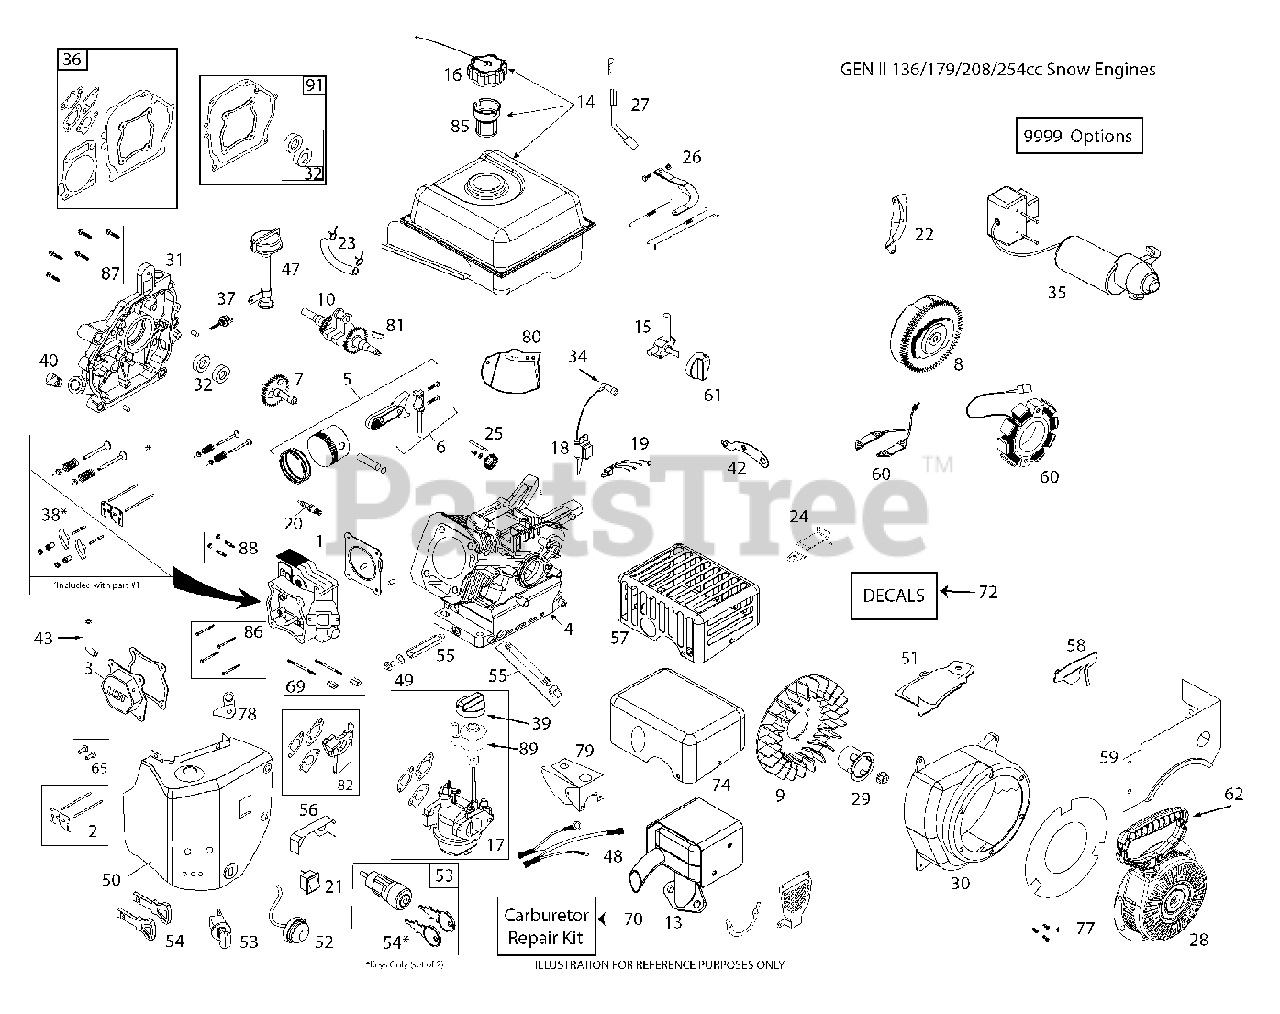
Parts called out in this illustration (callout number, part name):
1	Cylinder Head Assembly with Gasket, 254
2	KIT.PUSH.ROD.&.PLATE.W/VC.GASK
3	COVER.VALVE.W/GASKET.254CC
5	PISTON.&.ROD ASSEM.254CC
7	CAMSHAFT.MCR.W/GASKET.254CC
8	FLYWHEEL.ELEC.STRT.(8.MAGNETS)
9	KIT.COOLNG.FAN.SERV(SK208-4000
10	CRANKSHAFT.KEYED(#18).SNOW.254
13	MUFFLER.ASSEM.GEN2.SNOW.254CC
14	FUEL.TANK.SNOW.2.7L.BLACK.254C
15	FUEL.PETCOCK.SNOW(SKSN4900)
16	FUEL CAP OVERSIZED CLICK STYLE
17	Carburetor, LCT 254 with Idle-Down
18	COIL.ING.CDI.HI TEMP.SKSNO416.
20	PLUG.SPARK.PLAT.SKSN2404.1
21	SWITCH.ON/OFF(SKSN-0403)
22	SHIELD.FLYWHEEL.ELEC.STRT.208C
23	FUEL HOSE KIT
24	BRACKET.SPEED.CNTRL.FIXED.254C
25	GOVENOR.GEARS ASM(SK2082900)
26	KIT.GOVERNOR.ARM.&.LINK.254CC
27	KIT.GOVERNOR.CRANK(SK208-3100)
28	RECOIL.STRT.ROUND(BLK) SNOW
29	STRTER.CUP(NON-SLOT)SKSN0601.2
30	BLOWER HOUSING.LCT.208.ES W/OIL
31	CRANKCASE.CVR.PRESS.IN.HI-OIL.
32	Oil Seal Kit, 2 Pieces 254CC
34	SPARK.PLUG.BOOT.SNW,SKSN4691.1
35	ELEC.START.GEN2.SKSN0400.2
36	KIT.ENGINE.GASKET.254CC
38	KIT.ROCKER.ARM.W/GASKET.254CC
39	CHOKE.KNOW.SNOW(SKSN4500)
40	NON REMOVABLE PLUG
43	TUBE.BREATHER.LCT.208
47	High Oil Fill Tube Assembly
48	WIRE.HARNESS.SNOW
49	KIT.OIL.DRAIN.PLUG(SK2089911
50	KIT.HEATER.BOX.SNOW.254CC
52	PRIMER.BULB.WITH HOSE (SNOW)
53	SWITH.KEY.ASSEM.SNOW.SINGLE.ST
54	KEY SET(2 KEYS) SKSN0407.1
55	OIL PIPE DRAIN LCT 254
56	SHIELD.CARBURETOR.VAPOR
58	SHIELD.GOVERNOR.LINKAGE.254CC
59	FUEL TANK SKIRT SHIELD LCT 254
60	208CC 60W ALTERNATOR
61	FUEL KNOB-SNOW
62	HANDLE.RECOIL.DEL.SKSN0613.1
65	TAPPET.KIT.LCT.208CC
69	CARB.STUDS & COUPLING KIT.SNOW
70	Carburetor Repair Kit, LCT SK9900
74	Muffler Heat Shield Cover
77	Recoil Bolt Kit, LCT
79	COVER.CARBURETOR.SNOW
80	SHIELD.GOVERNOR.LINK.SNOW.254C
81	Flywheel Keys, 136/291cc 5-Pack
82	Carburetor Spacer, 208cc Lct
85	Fuel Tank Strainer, LCT 208cc
86	KIT.BOLT.CYLINDER.HEAD.(4PC)
87	KIT.BOLT.CRANKCASE.COVER.6PC
88	STUD.MUFFLER.KIT.LCT
89	Speed Knob, LCT Sksn5325.1
91	CRANKSHAFT GASKET KIT.LCT
9999	High Altitude Jet, LCT >5000 25
